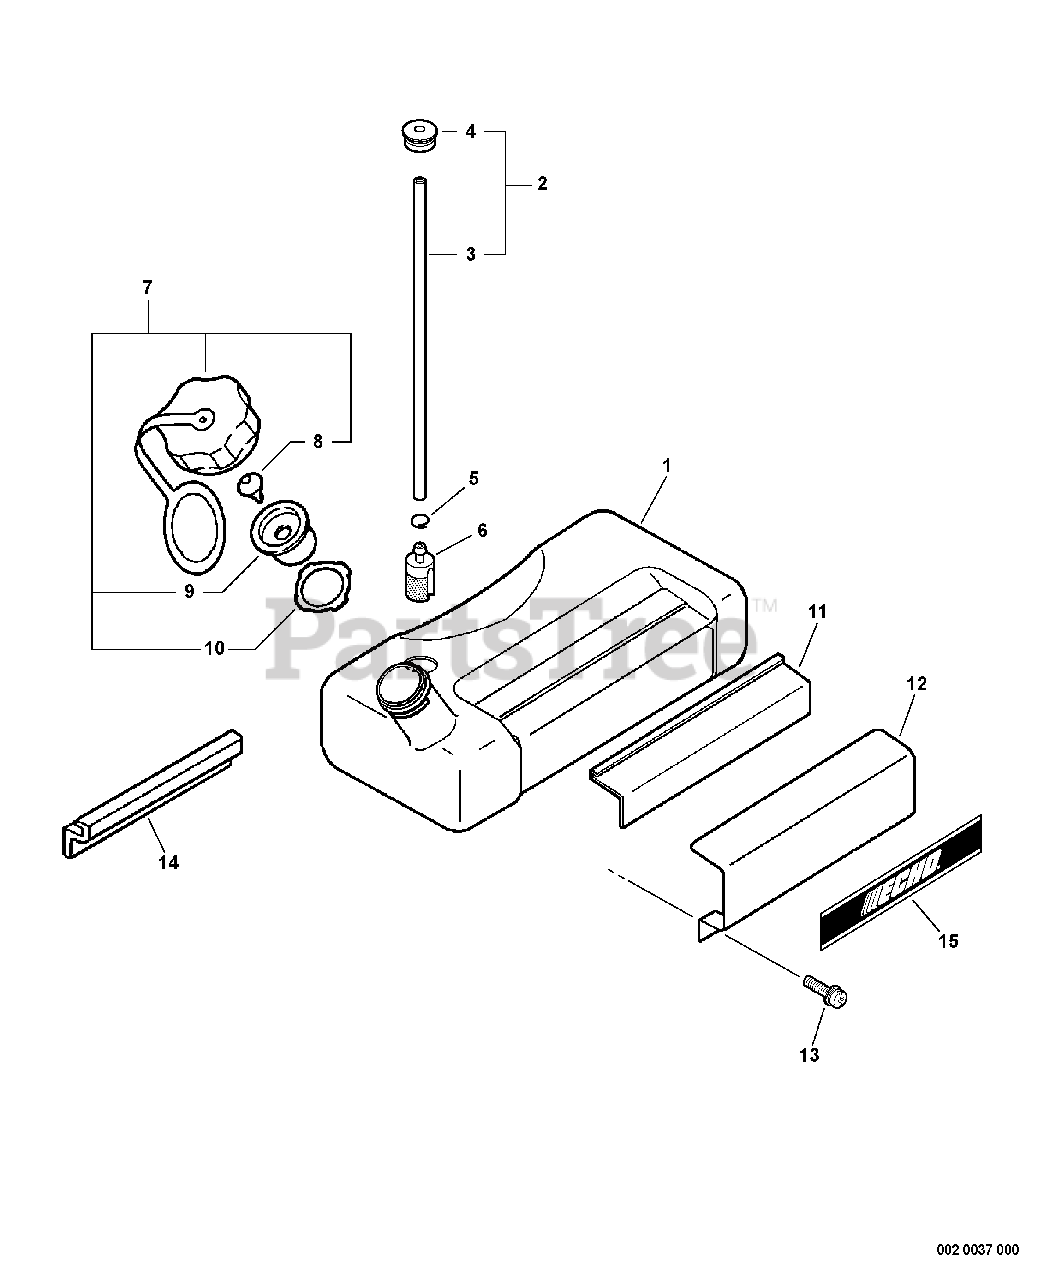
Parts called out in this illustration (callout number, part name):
1	TANK, FUEL
2	PIPE, FUEL W/GROMMET 3×5×250L
3	PIPE, FUEL W/GROMMET 3×5×250L
5	CLIP 6 MM
6	FILTER, FUEL
7	CAP ASSY, FUEL
8	VENT ASSY
9	HOLDER, VENT
10	GASKET, FUEL CAP
11	CUSHION, FUEL TANK
12	BRACKET, FUEL TANK
13	SCREW 5×10
14	SEAT, FUEL TANK
15	LABEL - ECHO
